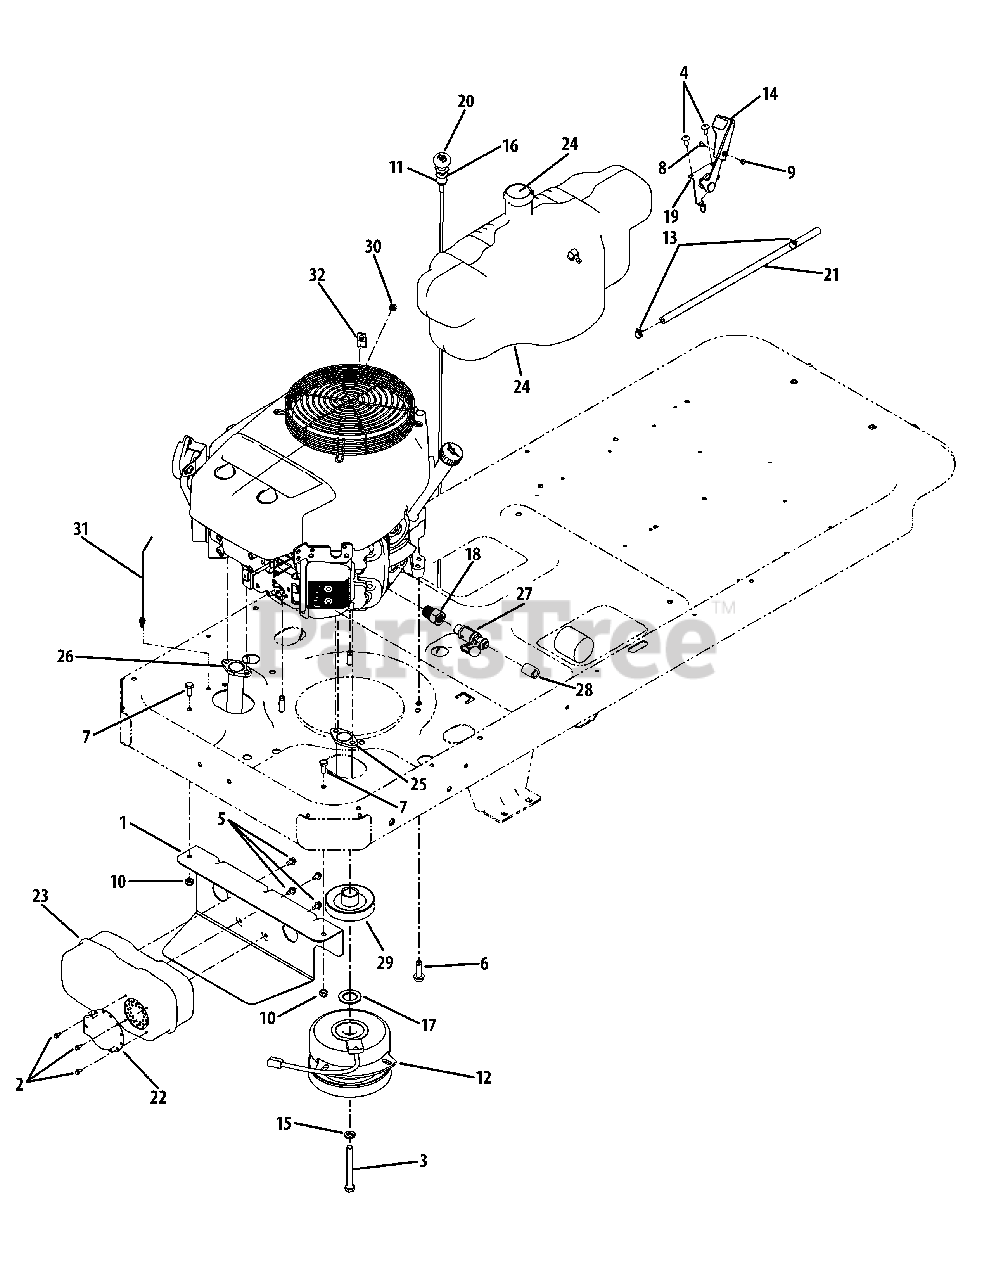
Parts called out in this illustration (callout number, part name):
1	Muffler Mounting Bracket
2	Hex Washer Head Screw, #8-18 x .5
3	Hex Cap Lock Screw, 7.16-20 x 3.5
4	AB Screw, 1.4-14 x .625
5	Hex Washer Head Screw, 1.4-20 x .5
6	Hex Washer Hd. Screw, 3.8-16 x 1.25
7	Hex Cap Screw, 5.16-18 x .75
8	Truss Hd. Mach. Screw, #8-32 x .375
9	Hex Nut, #8-32
10	Hex Insert Lock Nut, 5.16-18
11	Hex Jam Nut, 3.8-16
12	Electric PTO Clutch Assembly
13	Hose Clamp
14	Throttle Control Knob
15	Lock Washer, 7.16
16	Flat Washer, .406 x .875 x .059
17	Flat Washer, 1.031 x 1.62 x .095
18	Hex Fitting
19	Throttle Cable, 34.25 LG
20	Choke Cable, 61 LG
21	Fuel Line Hose
22	Muffler Deflector
23	Muffler
24	Fuel Tank
24	Fuel Tank Bushing
24	Fuel Pick-Up Bushing
24	Fuel Cap
25	Exhaust Pipe, RH
26	Exhaust Pipe, LH
27	Oil Drain
28	Oil Drain Extension Hose
29	Drive Pulley
30	Sems Nut, 1.4-20
31	Push Mount Cable Tie
